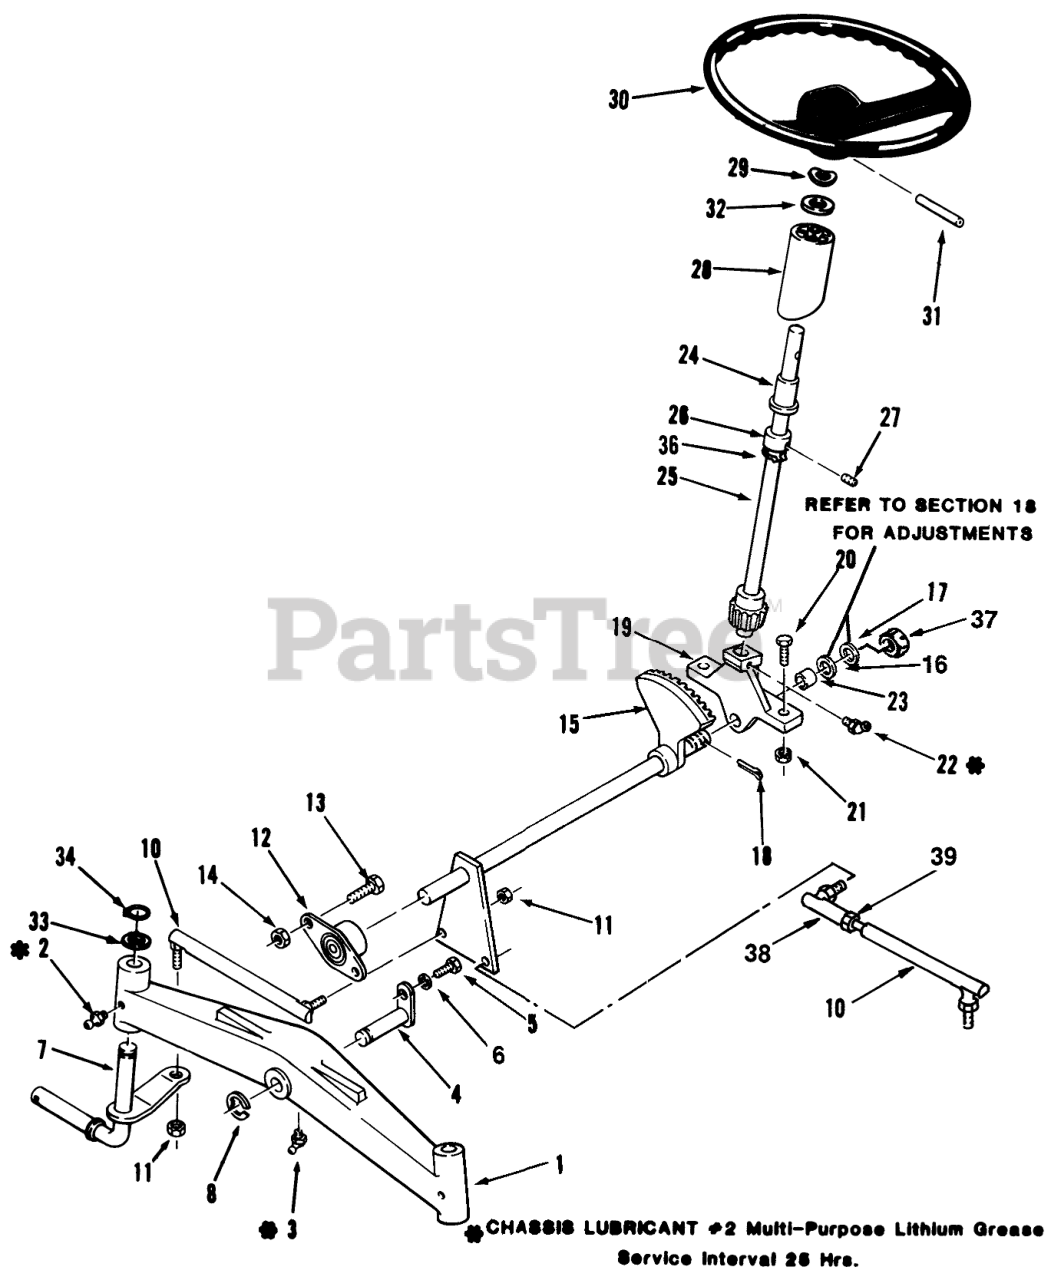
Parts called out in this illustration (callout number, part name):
1	AXLE-FRONT
2	Zerk
3	FITTING-GREASE
4	PIN AND PLATE ASM
5	H H C S
6	Lockwasher
7	RH SPINDLE WA
8	E-RING
10	Tie Rod (Incl. Ref. #38)
11	Nut
12	BEARING-FLANGED
13	Bolt
14	NUT
15	Shaft
16	WASHER-SHIM
17	WASHER
18	Cotter Pin
19	Support
20	Bolt
21	Nut
22	FITTING-GREASE
23	BEARING-BRONZE
24	BEARING-FLANGED
25	Shaft-Upper Steering
26	Collar
27	SCREW-SET
28	TUBE-STEERING
29	WASHER-BOWED
30	Steering Wheel 310-8 (Incl. Ref. #40)
31	Pin-Roll
32	WASHER-FLAT
33	WASHER
34	Snap Ring
36	RING-RETAINING
37	Nut-Slotted 3/4-16
38	BALL-JOINT
39	NUT-6
40	STRG-WHL INSERT TORO
